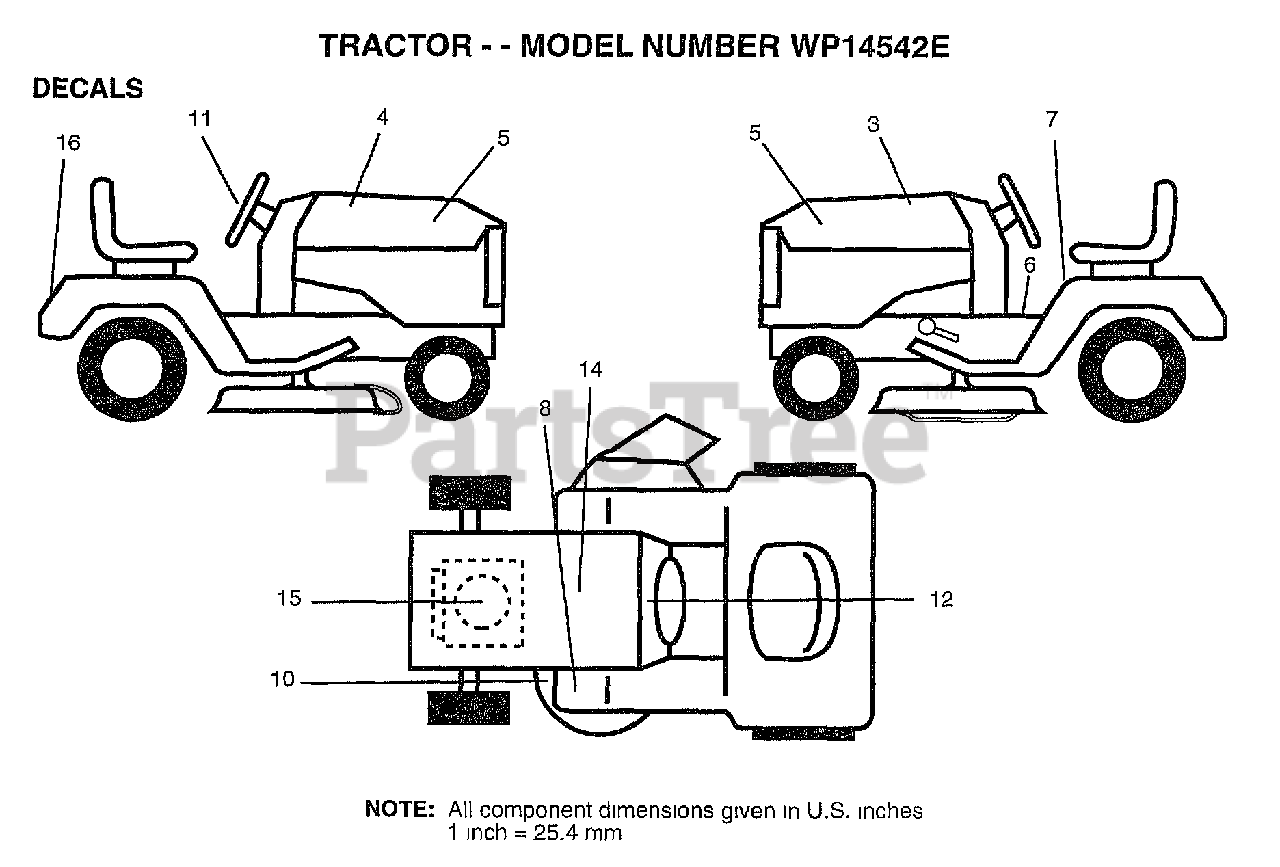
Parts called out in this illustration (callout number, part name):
3	DECAL.HOOD.LH
4	DECAL.HOOD.RH
5	DECAL.INS.HD.LT.
6	DECAL BRAK PARK
7	"DECAL DANGER,FEND"
10	"DECAL-SCHEM,BELT"
11	DECAL, INSERT
12	"DECAL-OPER,GEAR D"
14	DECAL.BATRY.3-3908
15	DECAL, ENGINE
16	DECAL, FENDER LOGO
